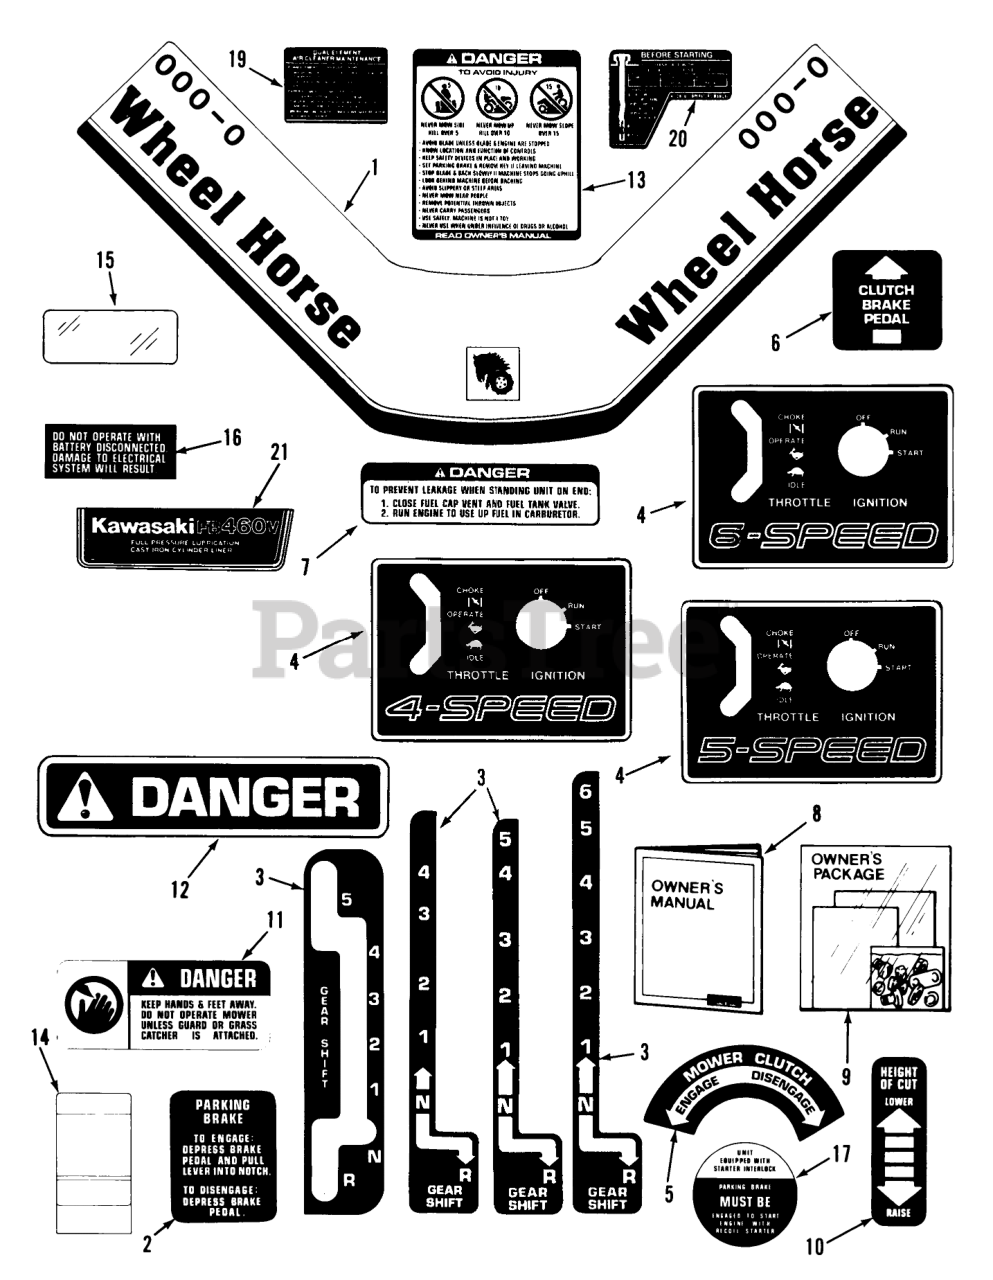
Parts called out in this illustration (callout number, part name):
1	Front Steering Shroud Decal 108-4 Only
2	DECAL PARKING BRAKE
3	DECAL SHIFT 4SPD
4	DECAL 4-SPD
5	DECAL MOWER CLUTCH
6	DECAL CLUTCH & BRAKE
7	DECAL-DANGER
8	Owner-s Manual
9	Loose Parts Package 108-4 Only
10	DECAL-HOC
11	Danger Decal
12	Danger Decal
13	DECAL-DANGER
14	Decal-Maintenance
15	DECAL-OVERLAY
16	DECAL ELECT SYSTEM
17	DECAL-ENGINE START
19	Decal-Air Cleaner Maint. (vendor #56031-2191)
20	Decal-Engine Oil FB460V (vendor #56031-2249)
21	LABEL-BRAND
